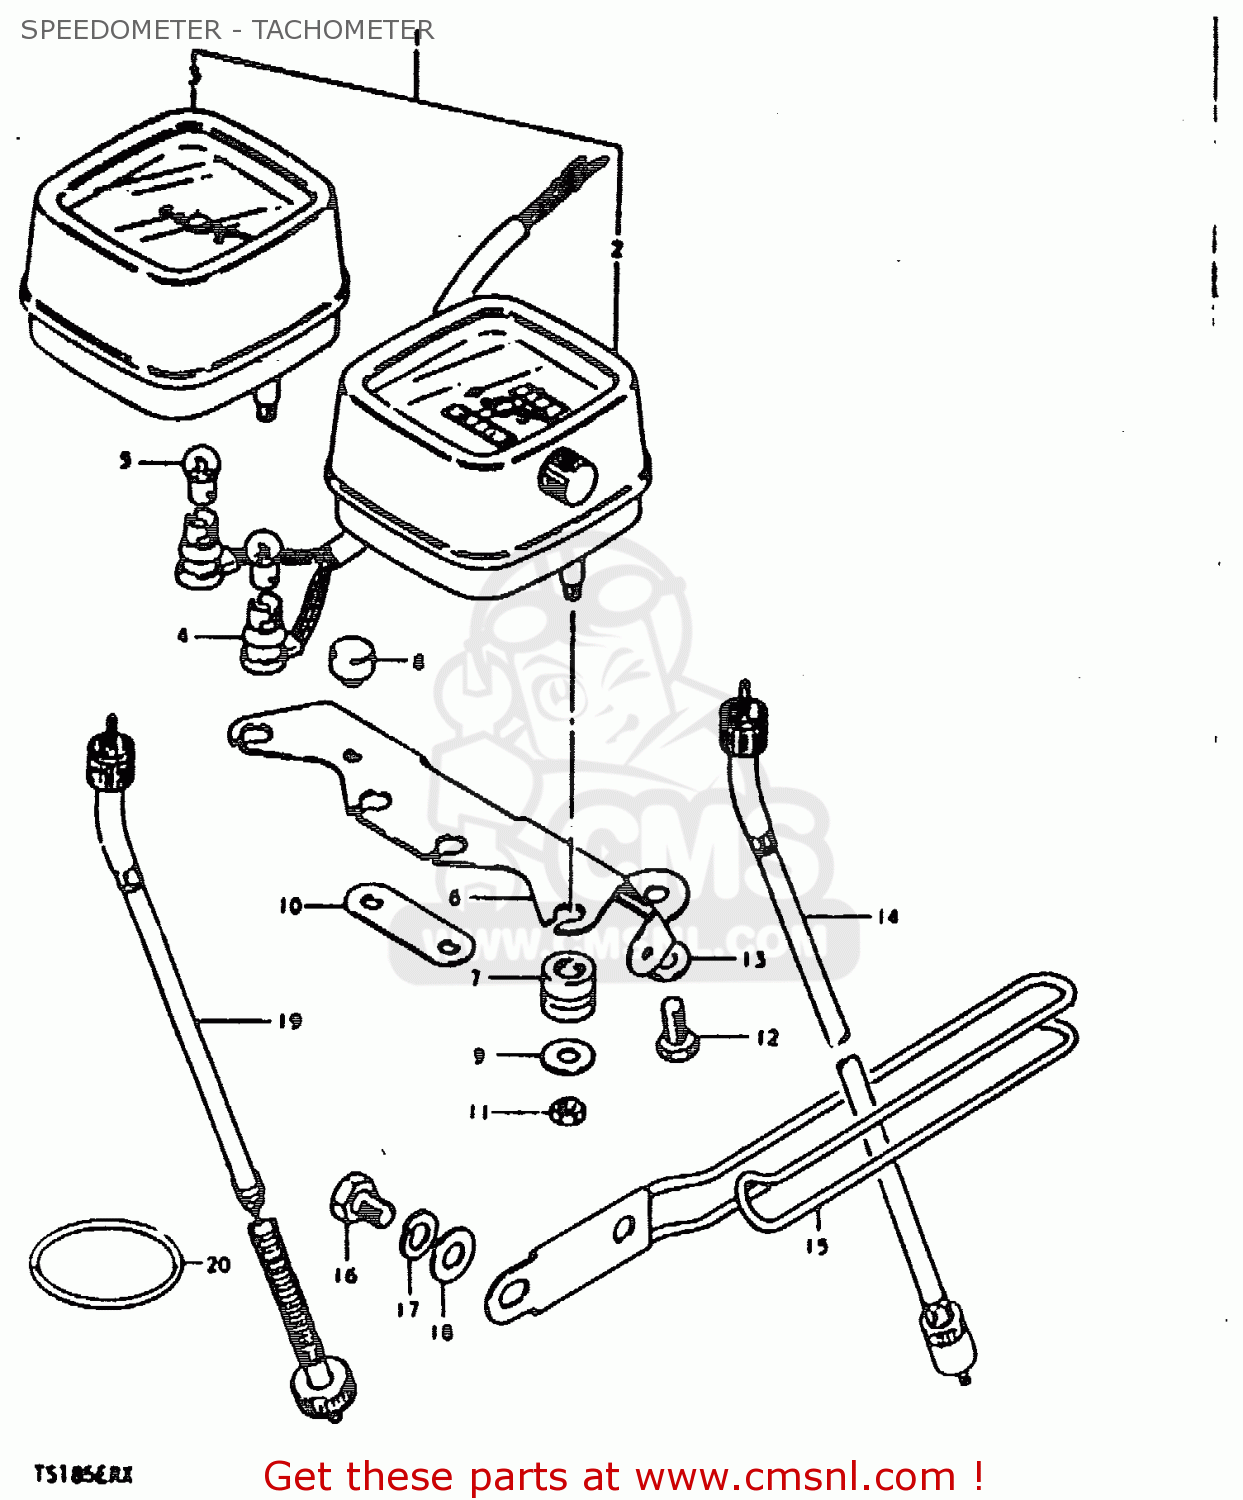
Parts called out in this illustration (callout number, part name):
1	SPEEDO/TACHOMETER ASSY (MILE/KILO SCALE)
2	SPEEDOMETER (MILE/KILO)
3	TACHOMETER
4	SOCKET
5	BULB(6V1.7W,STANLEY,A61A)
6	BRACKET
7	CUSHION
8	CUSHION,METER
9	WASHER,METER
10	PLATE,CONNECTING
11	NUT
12	BOLT, UPPER
13	WASHER
14	CABLE ASSEMBLY,SPEEDOMETER
15	GUIDE,CABLE
16	BOLT 8X12
17	LOCK WASHER
18	WASHER
19	CABLE, TACHOMETER
20	O RING,RR BRAKE CABLE
